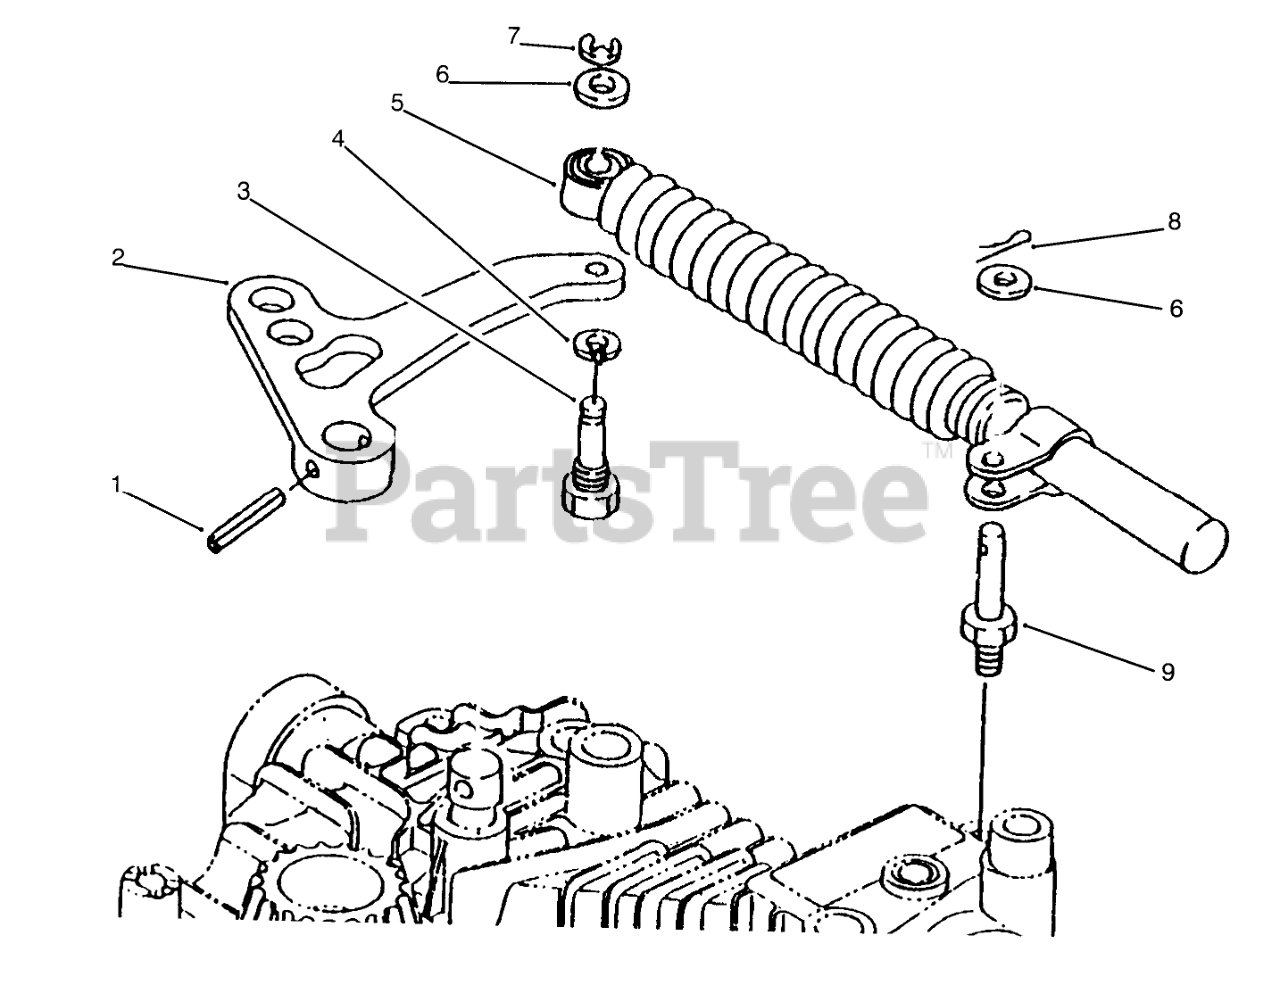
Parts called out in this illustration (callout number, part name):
1	PIN-ROLL
4	WASHER
5	ABSORBER - SHOCK
6	WASHER
8	PIN-COTTER
